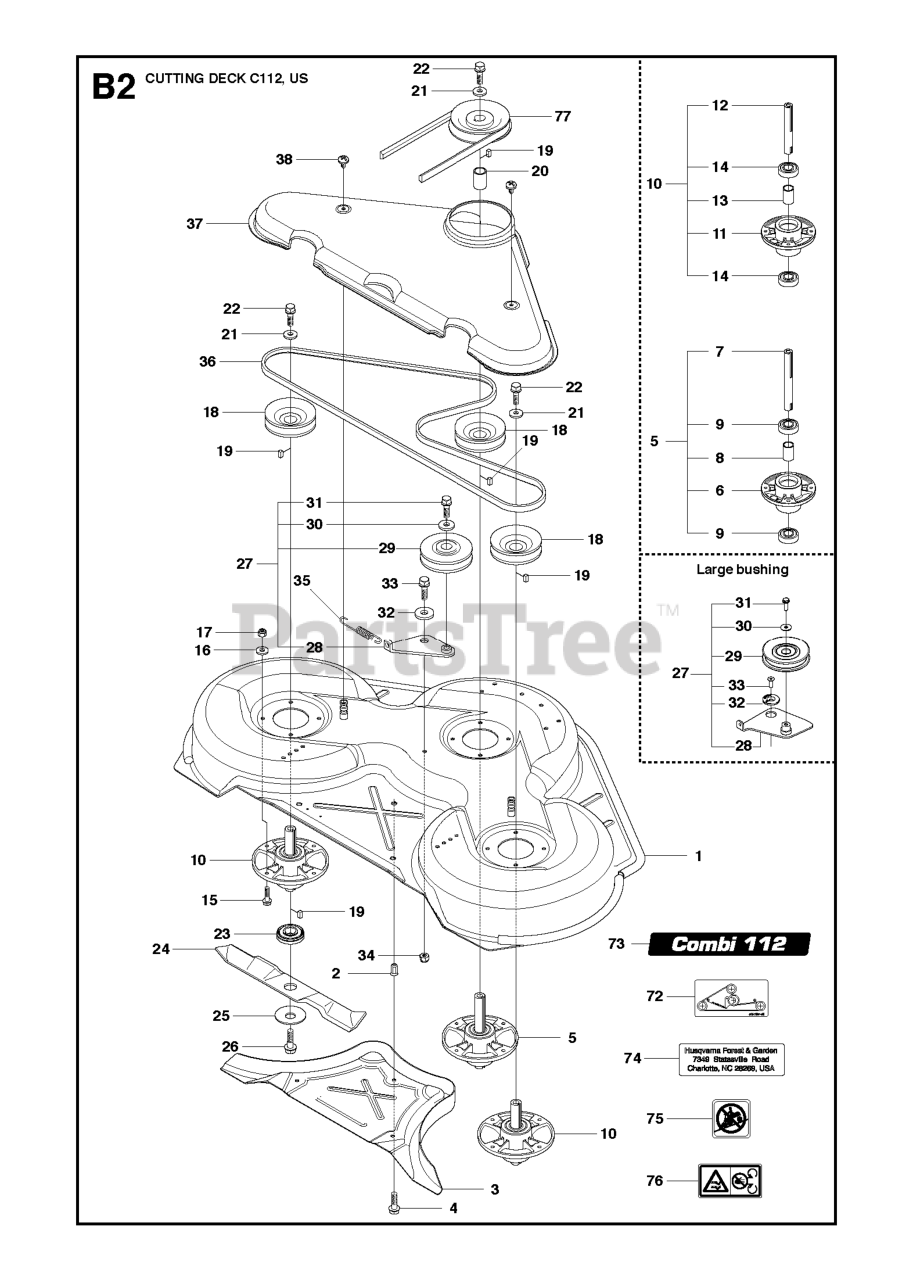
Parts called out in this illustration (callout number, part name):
1	CUTTING DECK
5	BLADE HOUSING ASSY
6	BEARING HOUSING
8	SPACING SLEEVE
10	BLADE HOUSING ASSY
11	BEARING HOUSING
13	SPACING SLEEVE
16	WASHER BRB 8.4X17
17	LOCKNUT M8
25	WASHER
27	BELT TENSIONER ASSY
27	BELT TENSIONER ASSY KIT
28	BELT TENSIONING ARM
31	BOLT
32	WASHER SHOULDER ASSY
32	WASHER
33	SCREW
34	LOCKNUT M8
36	BELT
37	BELT COVER
